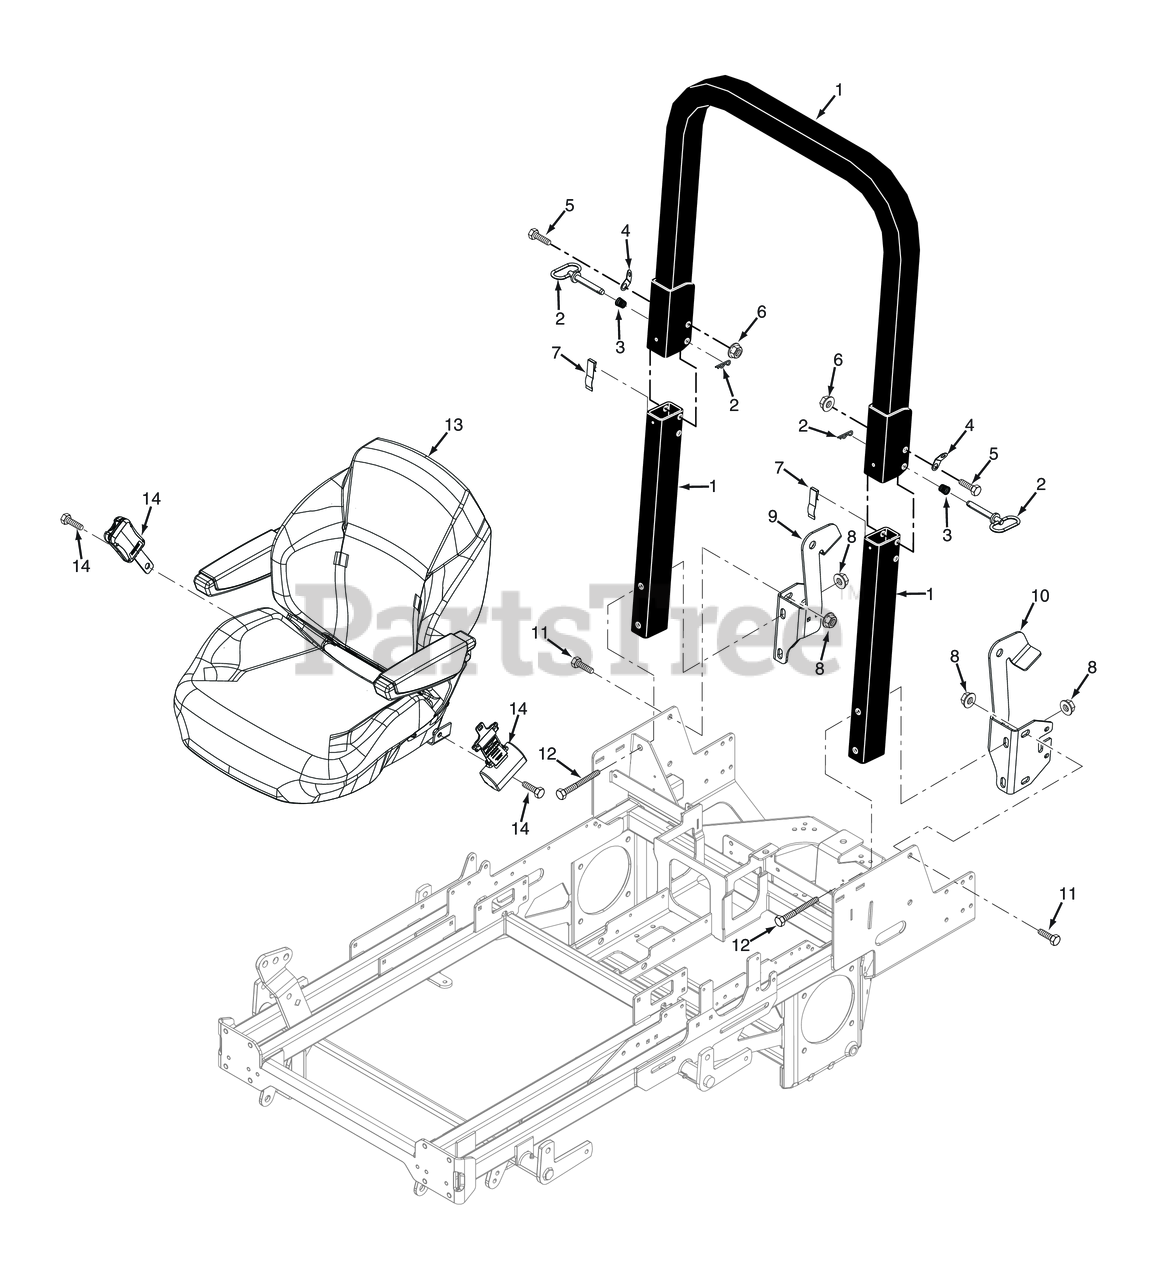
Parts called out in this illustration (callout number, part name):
1	ROPS, Foldable SCZ
2	Pin Assembly, ROPS Hinge
3	Spring, ROPS
4	Clip, ROPS
5	Bolt, Hex Head, 1/2-13 x 3-1/4"
6	HEX LOCKNUT, ELASTIC STOP, 1/2-13
7	Spring, ROPS Anti-Rattle
8	Nut, Elastic Stop 1/2-13, (STT-52 & STTII-52)
9	ROPS Mount, RH, 29CV-EFI
10	ROPS Mount, LH, 29CV-EFI
11	Bolt, Hex Head 1/2-13 x 1-1/4"
12	Bolt, Hex Head 1/2-13 x 4-1/4"
13	Seat Assembly (INCL 14)
14	Seat Belt Kit, Retractable - SCZII
